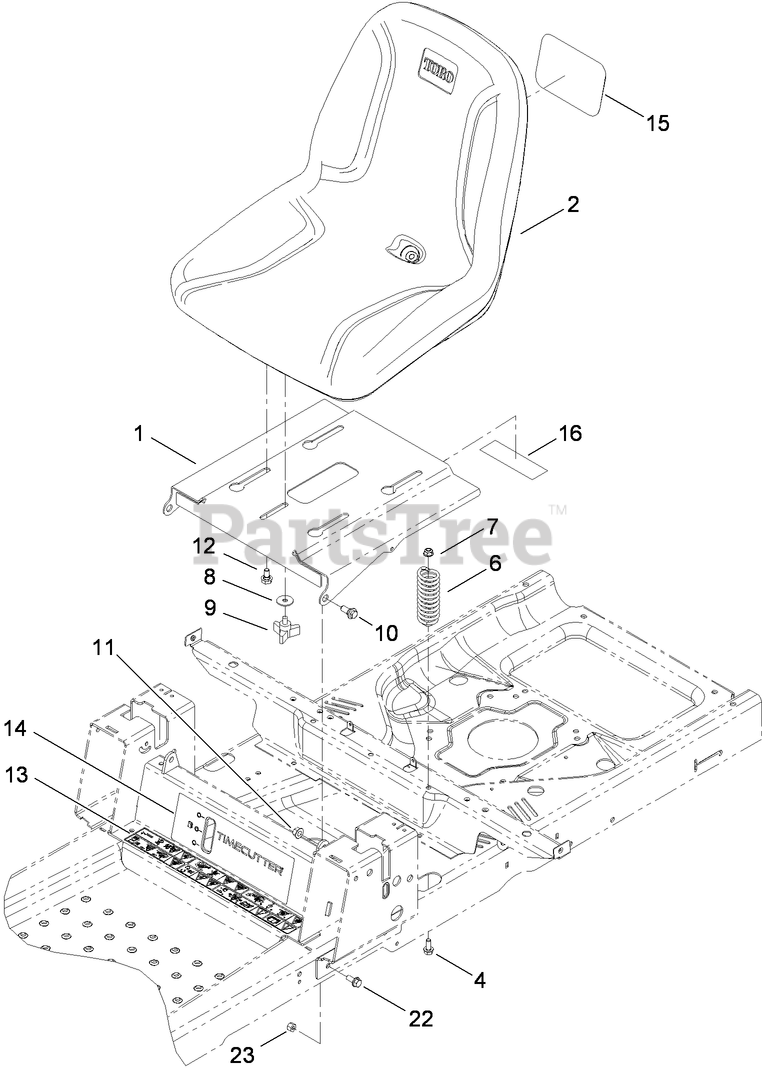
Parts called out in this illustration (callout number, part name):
1	BASE-SEAT
2	SEAT-18 INCH
4	SCREW-HHF
6	SPRING-COMPRESSION
7	NUT-HF, NI
8	WASHER-PIVOT
10	BOLT-SHOULDER
11	NUT-HF
12	BOLT-SHOULDER,HFH
13	DECAL-DANGER
14	DECAL-TIMECUTTER
15	DECAL
16	DECAL-SERVICE, CE
22	SCREW-HHF
23	NUT-LOCK, NI
